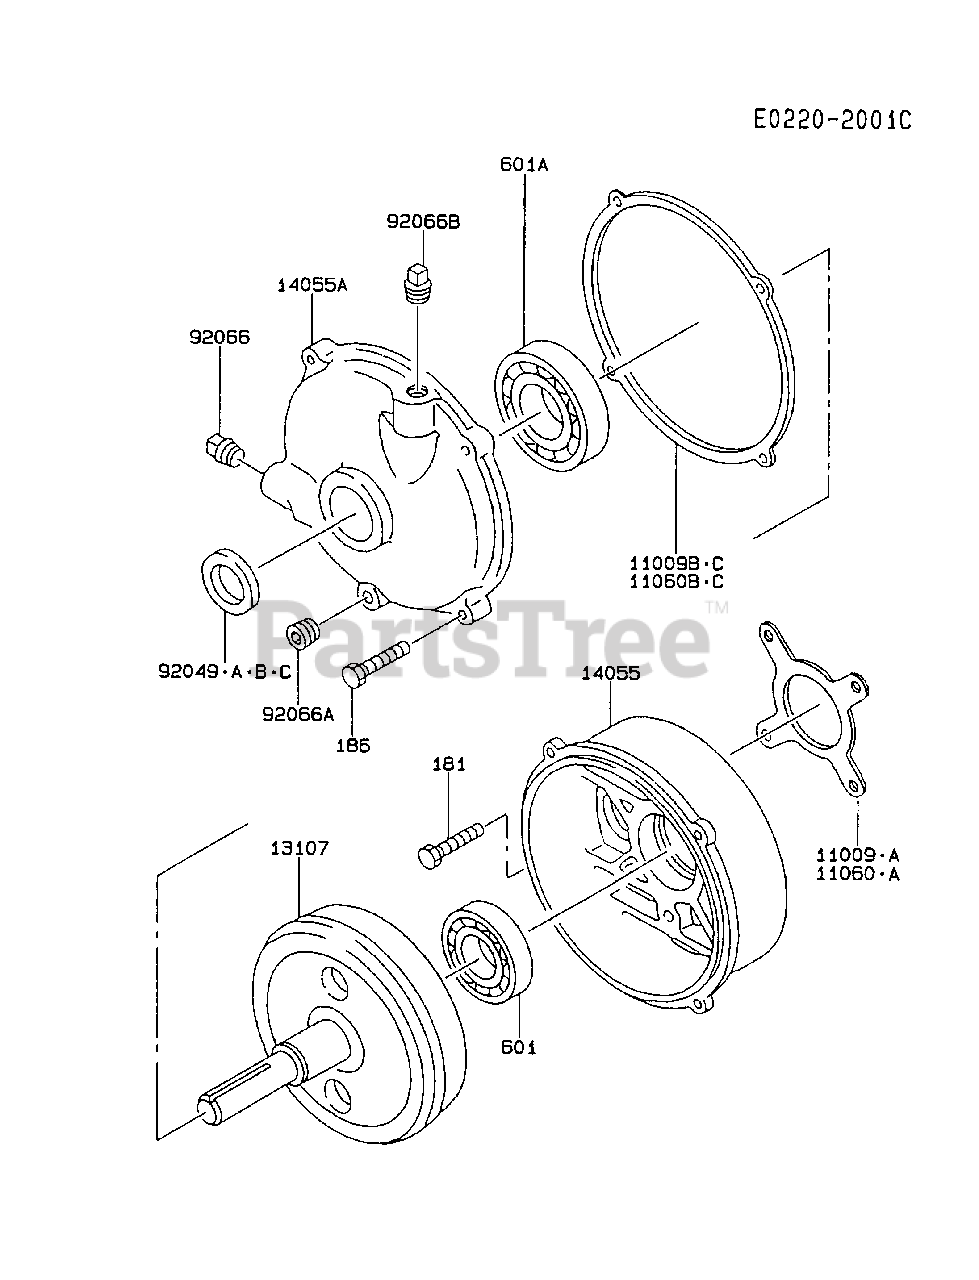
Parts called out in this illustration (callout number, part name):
181	BOLT-UPSET-WP
186	BOLT-UPSET-WP
601	BEARING-BALL
601A	BEARING-BALL
